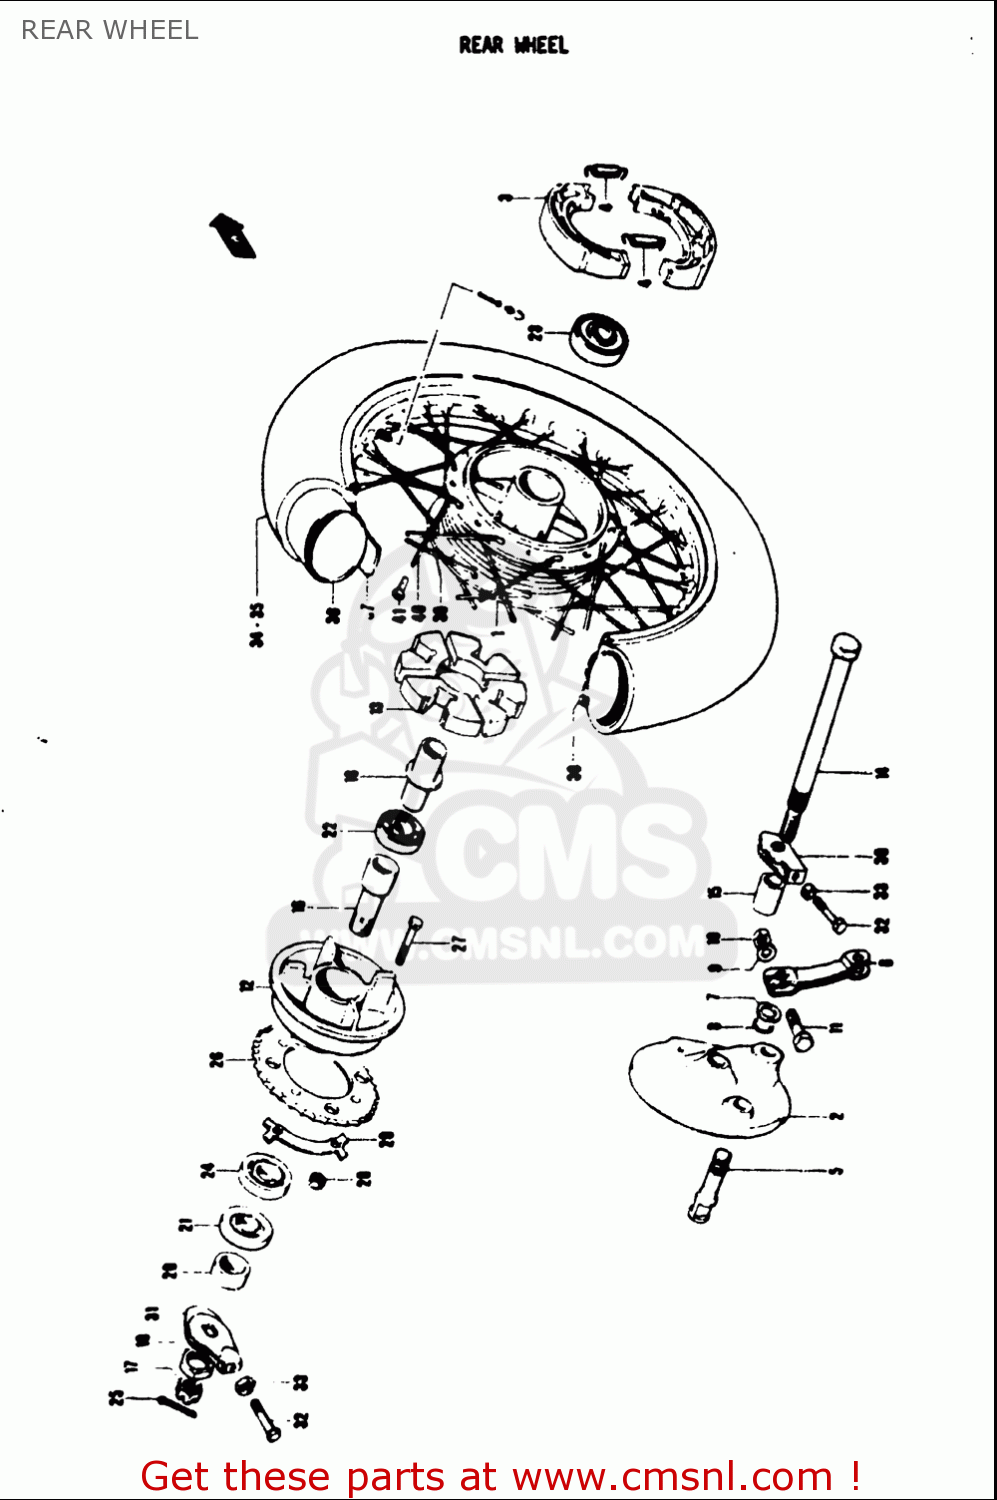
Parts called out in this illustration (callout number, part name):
3	SHOE & SPRING SET,BRAKE (NAS)
4	SPRING(L:35.8)
5	CAM,FR BRAKE
6	LEVER,RR BRAKE CAM
7	WASHER(12.5X20X1)
8	O RING(D:2.5,ID:11.4)
9	WASHER
10	NUT
11	BOLT(6X31)
13	ABSORBER,RR WHEEL HUB SHOCK
14	AXLE,RR
15	SPACER(12.2X22X30.5)
16	SHAFT,RR SPROCKET DRUM
17	NUT
19	NUT
20	SPACER(17X25X10.5)
21	SEAL,OIL(25X40X6)
22	BEARING
23	BEARING
24	BEARING(17X40X12)
25	COTTER PIN
26	SPROCKET,RR(NT:39)
27	BOLT(8X33.5)
29	WASHER
30	ADJUSTER,CHAIN,R
31	ADJUSTER,CHAIN,L
32	BOLT(6X38)
33	NUT
37	PROTECTOR,WHL INR TUBE
38	SPOKE SET,RR
